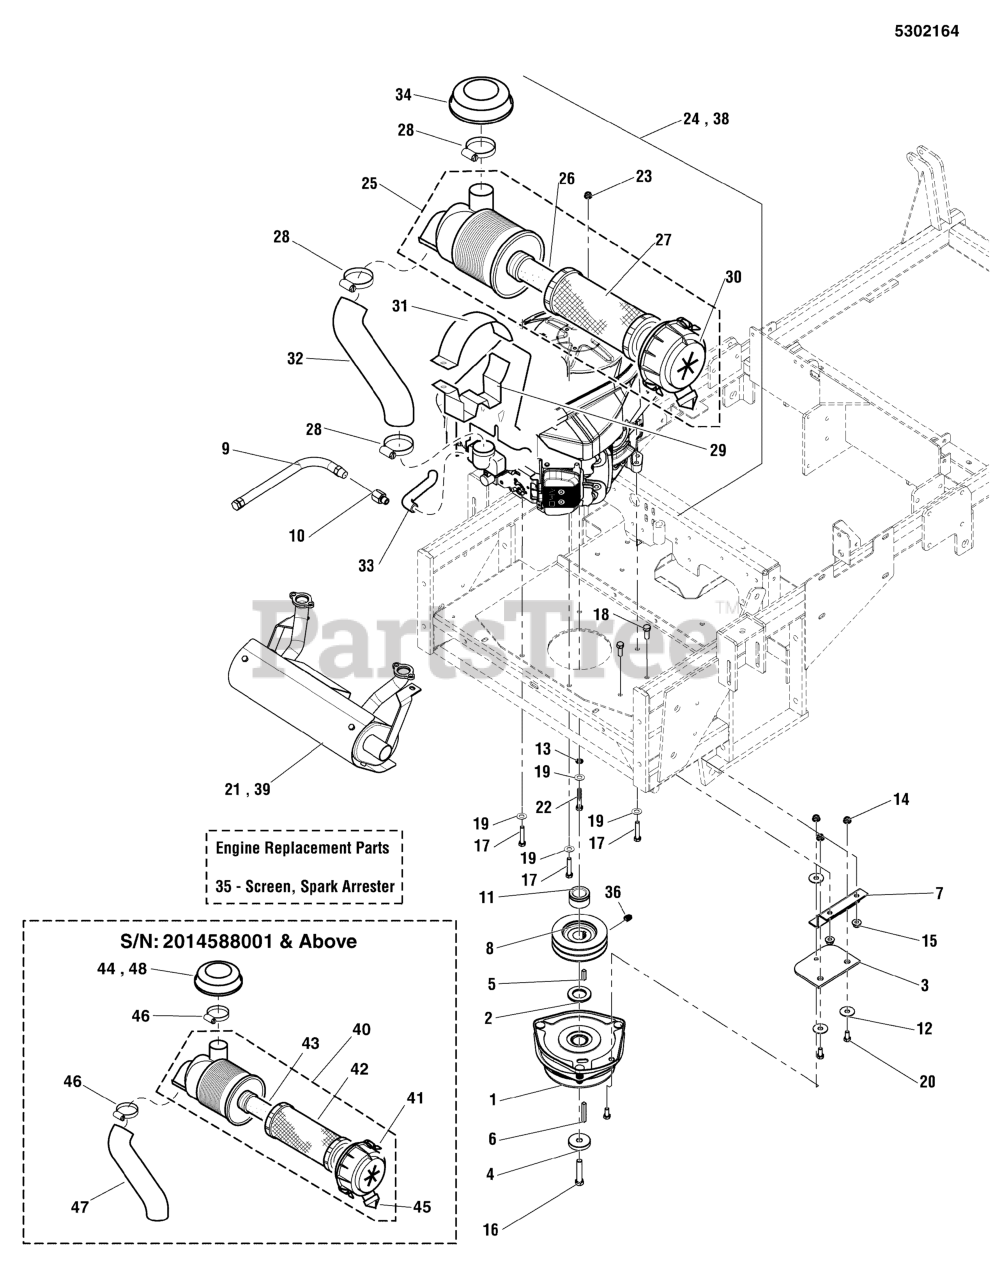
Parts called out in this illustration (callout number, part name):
1	CLUTCH, OGURA, 250 ft lbs - 1.13"
2	SPACER, 1.13 x 2.00 x .19
3	CLUTCH ANCHOR PAD
4	SPACER, .45 x 1.88 x .38
5	KEY, 1/4 SQ X 1
6	KEY, 1/4 SQ X 2
7	ANCHOR, CLUTCH - BLK
8	PULLEY, CRANKSHAFT, 1.126 ID X 4.75 OD
9	HOSE, OIL DRAIN
10	ADAPTER, Oil Drain
11	SPACER, 1.13 X 1.75 X 1.03, CZ
12	WASHER, 3/8" Fender
13	WASHER, 3/8" ID, INTERNAL TOOTH
14	NUT, 5/16-18 HEX NYLOCK FLANGE NUT
15	NUT, 3/8 - 16 HEX NYLOCK FLANGE
16	BOLT, CRANKSHAFT, 7/16" X 2-1/2"
17	BOLT, HEX FLG, SER, GD5 3/8-16 X 1-1/4" PACH CZ
18	BOLT, 3/8-16 X 1" GD5 CZ
19	WASHER, 3/8 SAE
20	BOLT, 5/16-18 X 3/4 GD5
21	MUFFLER 35-37HP KAWASAKI 5 CAN
22	BOLT, 3/8-16 X 2-1/4" GD5 TFL
23	NUT, Hex, Side Lock, 3/8-16
24	ENGINE, KAWASAKI
25	AIR FILTER ASSEMBLY (SV)
26	AIR FILTER, ELEMENT, SECONDARY
27	AIR FILTER, ELEMENT, PRIMARY
28	CLAMP, CAP
29	BRACKET PLATE, LOWER 34 & 37 (SV)
30	CAP END, FILTER CASE (SV)
31	BRACKET PLATE, UPPER 27, 34 & 37 (SV)
32	AIR INLET TUBE (SV)
33	BREATHER TUBE (SV)
34	RAIN CAP, KAWA, DFI
36	SET SCREW, 5/16-18 X 3/8, KNURL, W/PATCH
38	ENGINE, KAWASAKI DFI
39	MUFFLER 35-37HP KAWASAKI 5 CAN
40	AIR FILTER ASSEMBLY, 22,24&26HP KAWASAKI (SV)
41	CAP END, FILTER CASE, 22,24&26HP, KAWASAKI (SV)
42	AIR FILTER, PRIMARY,22,24&26HP, KAWASAKI (SV)
43	AIR FILTER, SECONDARY, 22, 24&26HP KAWASAKI (SV)
44	RAIN CAP, AIR FILTER, 22,24&26HP, KAWASAKI (SV)
45	RUBBER, Dust Valve, 22,24&26HP KAWASAKI (SV)
46	CLAMP, HOSE
47	TUBE, AIR INLET
48	RAIN CAP, KAWA, DFI
